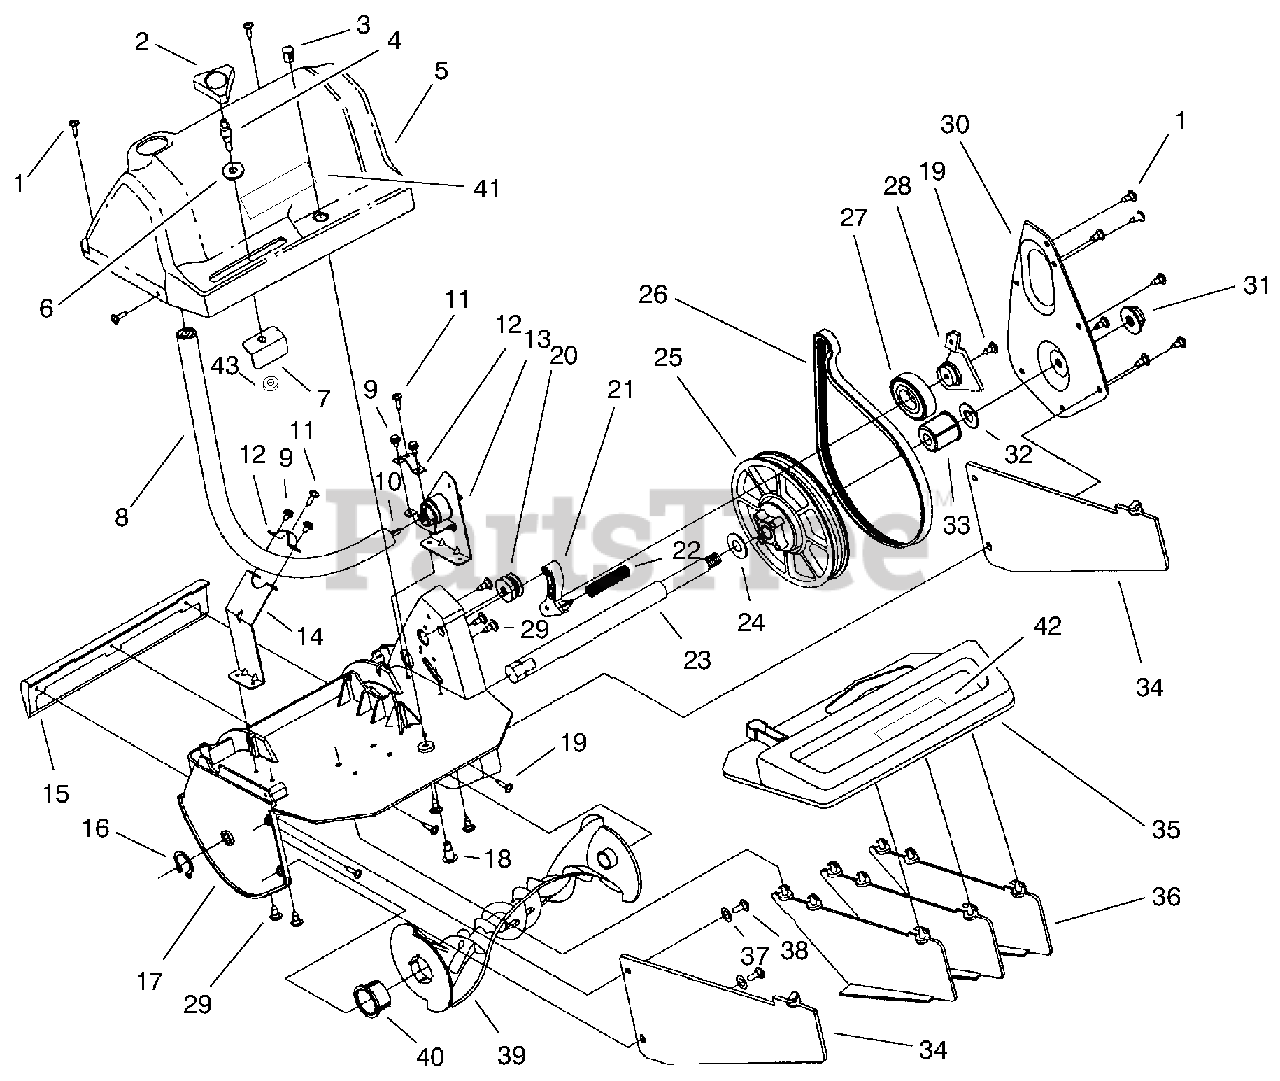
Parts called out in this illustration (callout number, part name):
2	Vane Actuator Knob
3	Grommet
4	Vane Actuator Shaft
6	Vane Actuator Washer
7	Vane Actuator Bracket
8	Drive Housing Assembly
10	Flexible Drive Shaft
13	Power Shaft Assembly
14	Drive Housing Bracket
16	Retaining Ring
17	Snowthrower Housing
20	Drive Pulley
21	Idler Arm
22	Idler Spring
23	Rotor Shaft
25	Driven Pulley
26	Drive Belt
27	Ball Bearing
28	Idler Pulley Retainer
30	Belt Case Cover
31	Flange Lock Nut
32	Thrust Washer
33	Left Rotor Bushing
34	Outer Vane
35	Vane Mount
36	Center Vane
40	Right Rotor Bushing
41	Decal-Lawn Boy
42	Decal-Impeller Danger
43	Palnut-Retainer
